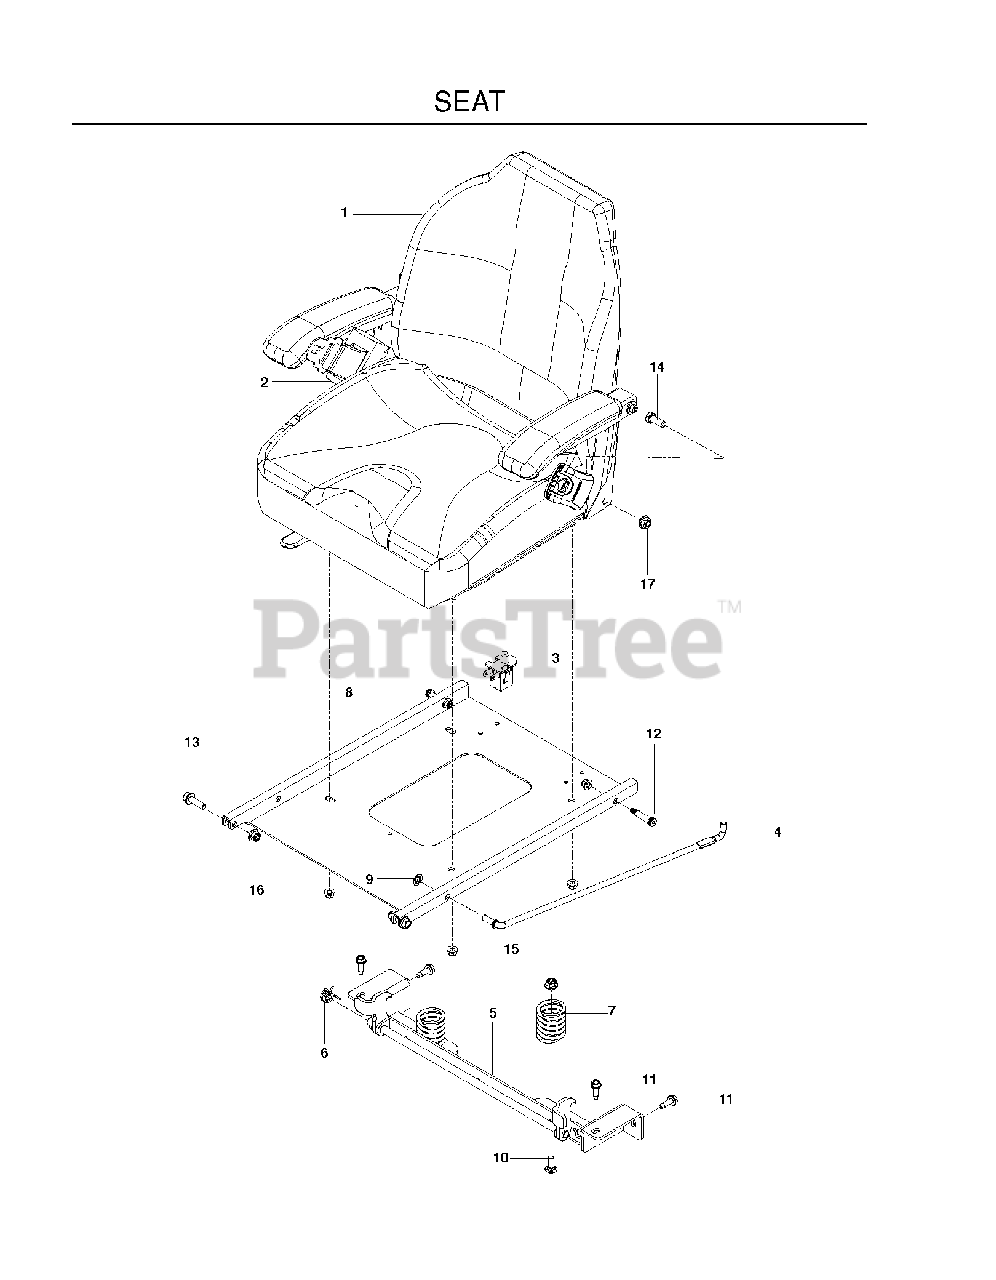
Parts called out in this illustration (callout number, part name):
1	SEAT.907.VINYL.HUSQVARNA
2	BELT, SEAT
3	SEAT SWITCH
5	LATCH.SEAT.BLACK
6	SPRING, TORSION
7	SPRING, SEAT
8	PAN, SEAT, BLACK
9	NUT 3/8 PALNUT RTNG BLK PHOS
10	RHSNB 3/8C X 1
11	RP BLT 5/16-18 X 1 THRD FORM D
12	BOLT, SHOULDER 3/8 X 1.25
13	HHFS 3/8-16 X 1.25 GD 5
14	HCS 7/16-14 X 1 GR 5 ZD
15	5/16-18 NYLOC FLANGE NUT
16	NUT 3/8-16 HEX FLG NYLOC ZD
17	NUT 7/16-14 HEX WHIZ LK
